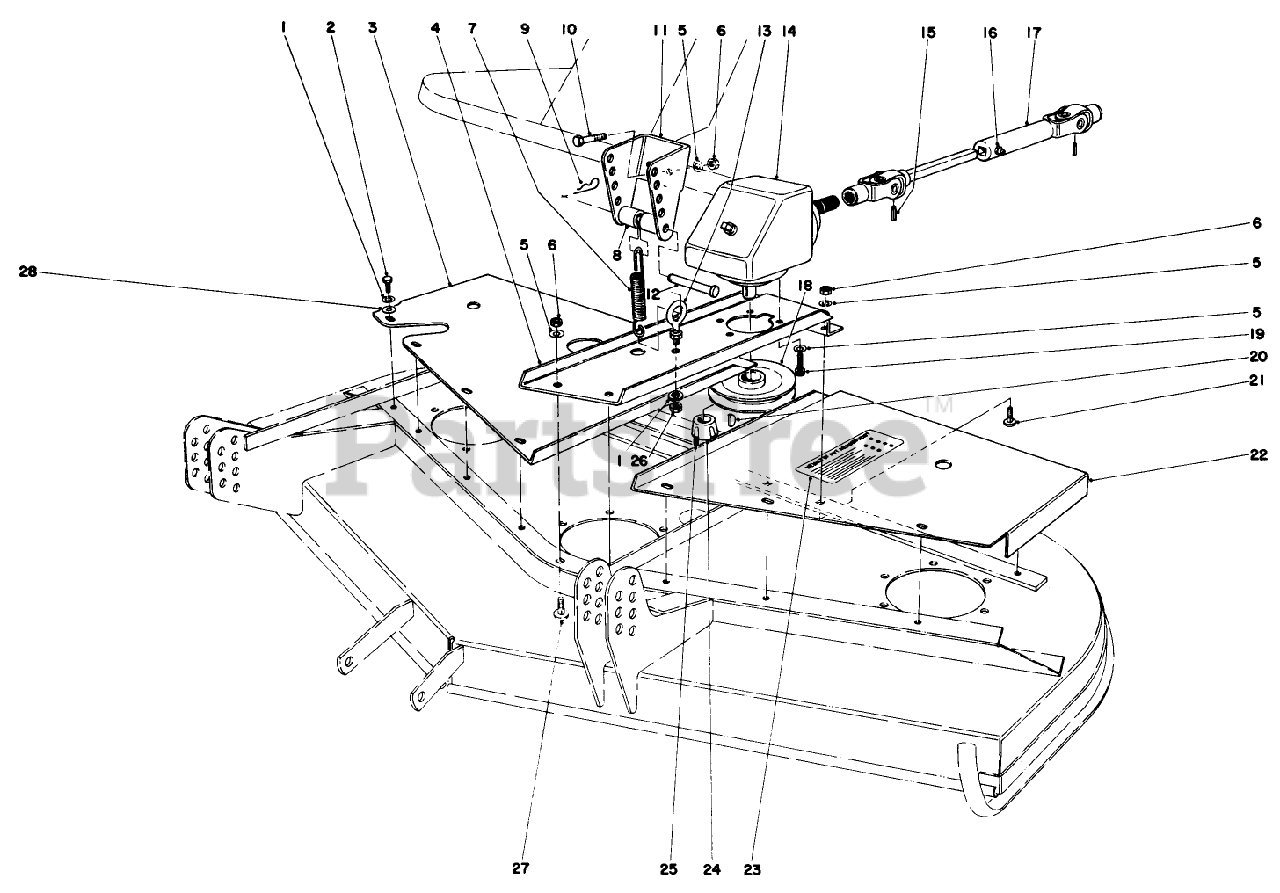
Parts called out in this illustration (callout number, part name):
1	WASHER-LOCK
2	SCREW THD 1/4 20 5/8
3	RH COVER WA R
4	Base-Bear Box
5	WASHER-LOCK
6	NUT-HEX
7	Extension Spring
8	SPACER
9	PIN-HAIR
10	SCREW-HH
11	Bracket-Spring
12	PIN-CLEVIS
13	Eye Bolt
14	GEAR BOX ASM
15	PIN-ROLL
16	FITTING-GREASE
17	Pivot Nut
18	PULLEY WA BO
19	SCREW-HSH
20	KEY-WOODRUFF
21	BOLT-CARR
22	LH COVER WA R
23	DECAL
24	BUSHING-LOCK, TAPER
25	SCREW-SET, HSH
26	NUT-HEX
27	SCREW-CARR
28	WASHER-FLAT
